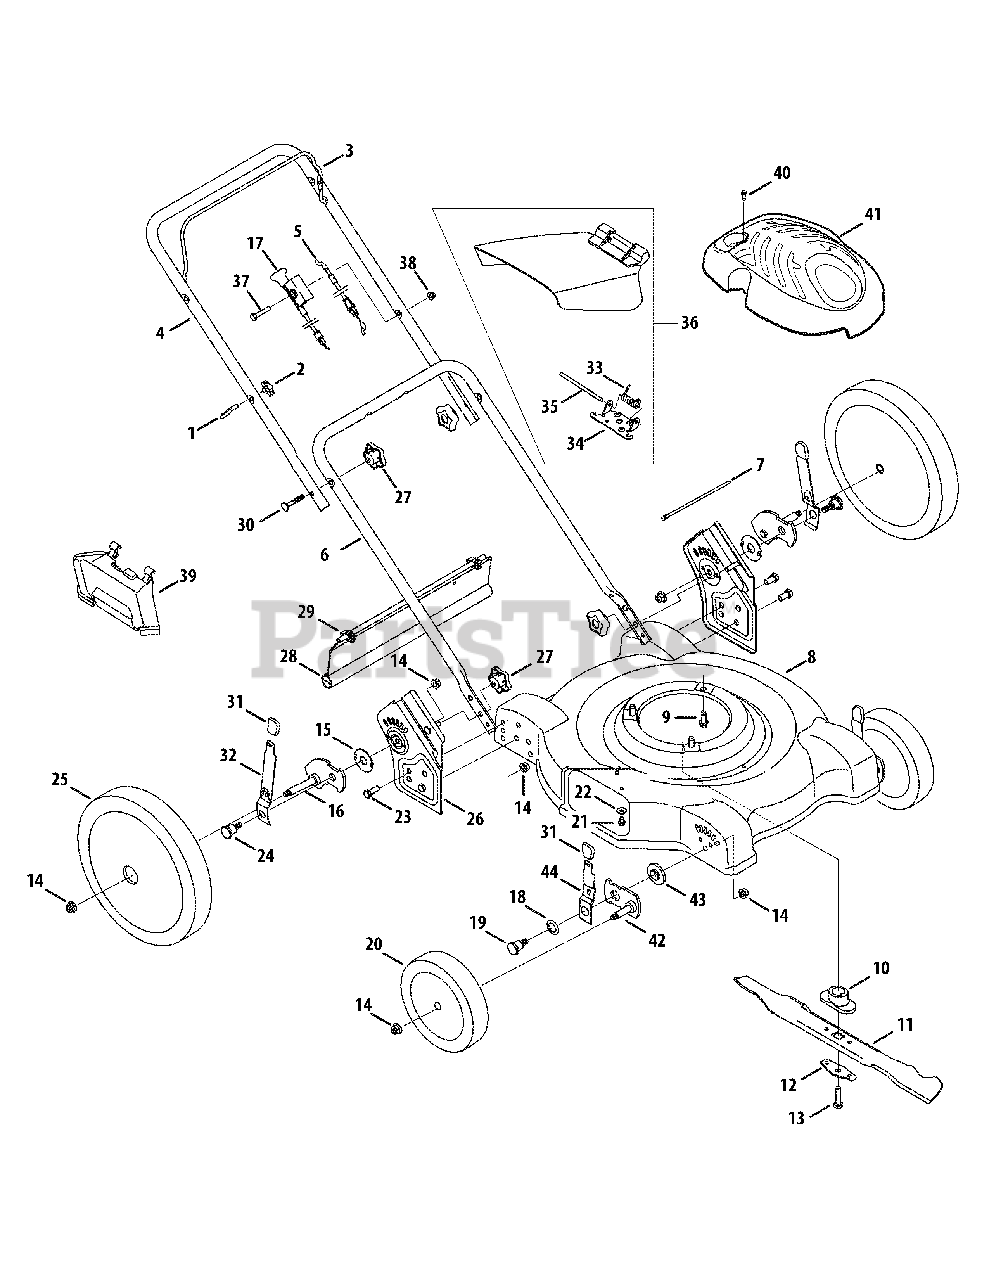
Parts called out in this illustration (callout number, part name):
1	Eye Bolt
2	Wing Nut
3	Blade Control Handle
4	Upper Handle
5	Control Cable
7	Cable Tie
8	Deck Assembly, 22"
9	TT Screw, 3/8-16 x 1.0
10	Blade Adapter
11	Mulching Blade, 22"
12	Blade Bell Support
13	Screw, 3/8-24 x 1.5
14	Lock Nut, 3/8-16
15	Thrust Bearing
16	Rear Pivot Arm - LH
16	Rear Pivot Arm - RH
17	Choke Cable
18	Bell Washer, .760 OD x 1.25 OD
19	Shoulder Screw
20	Front Wheel
21	TT Screw, 1/4-20 x .5
22	Bell Washer, .265 ID x .75 OD
23	Screw, 3/8-16 x .75
24	Shoulder Screw
25	Rear Wheel
26	Handle Bracket Assembly, RH
26	Handle Bracket Assembly, LH
27	Star Knob
28	Trailshield
29	Hinge Clip
30	Carriage Bolt, 5/16-18 x 2
31	Knob
32	Rear Lever
33	Torsion Spring
34	Chute Hinge
35	Hinge Pin
36	Hinged Chute Deflector Assembly
37	Screw, 1/4-20 x 1.50
38	Nut, Flange Lock, 1/4-20
39	Mulching Baffle
40	Screw, HL, #12-16 x 1.00
41	Engine Shroud
42	Front Pivot Arm
43	Height Adjuster Bearing
44	Front Lever
